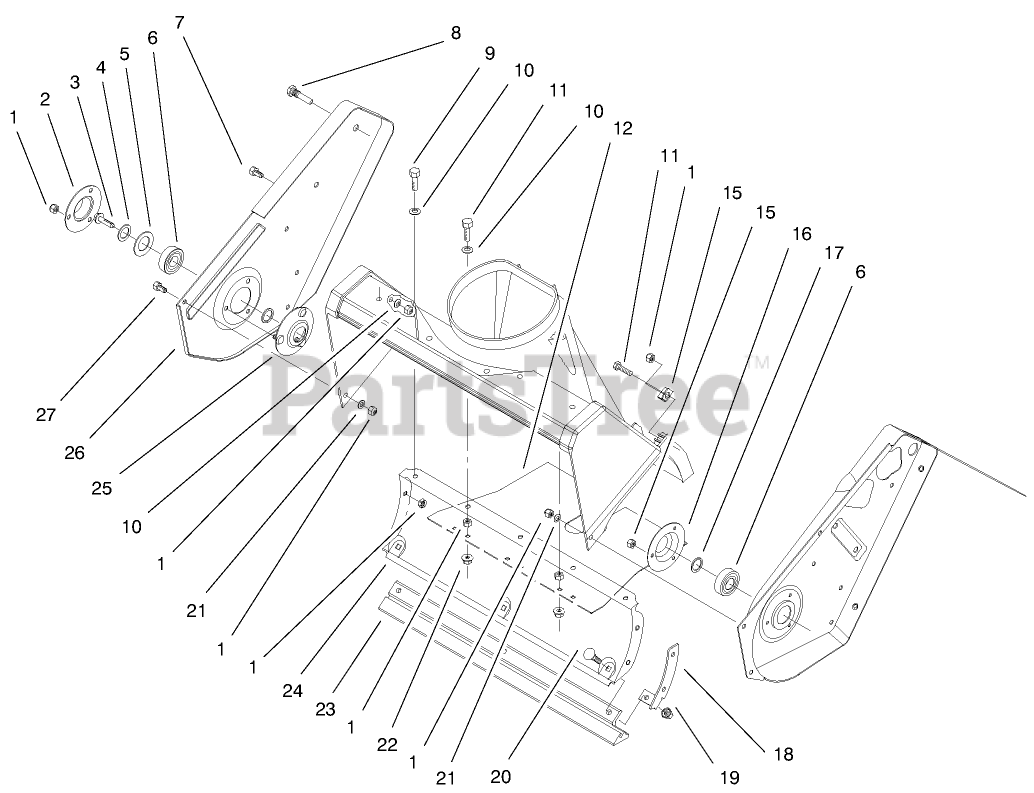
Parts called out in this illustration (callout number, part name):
1	NUT-LOCK, NI
2	Trough
3	SCREW-HHF
4	WASHER-FLAT
5	WASHER-RUBBER
6	BEARING-BALL
7	SCREW-HH
8	PIN-ROTOR
9	SCREW-HH
10	WASHER-FLAT
11	SCREW-HH
12	COVER-BOTTOM
14	BRACKET-HOUSING
15	NUT-LOCK, NI
16	FLANGE-BEARING
17	WASHER-THRUST
18	BRACKET-HOUSING, LOWER
19	NUT-KEPS
20	SCREW-CARR
21	WASHER-FLAT
22	NUT-LOCK, HHF
23	SCRAPER
24	HOUSING-LOWER
25	FLANGE-BEARING
26	PLATE-SIDE, RH
27	SCREW-HWH
